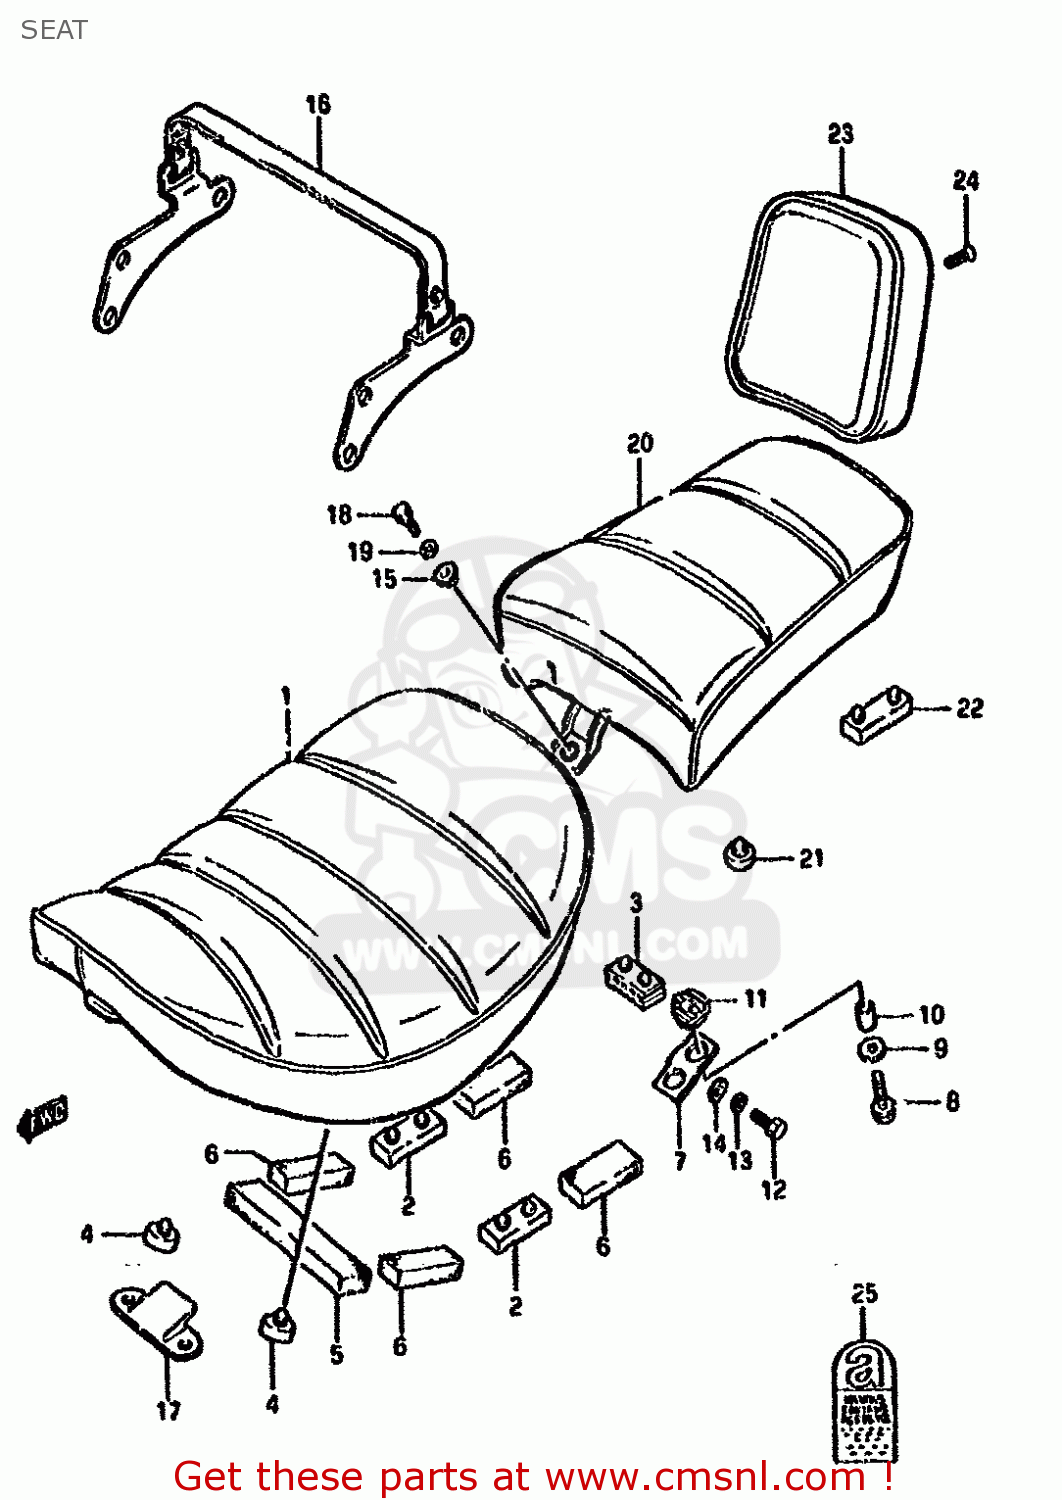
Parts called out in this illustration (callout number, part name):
1	SEAT SET
2	CUSHION,SEAT
3	CUSHION,SEAT(40X20X15)
4	CUSHION,FR
5	CUSHION,CTR FR
6	CUSHION,CTR SIDE
7	BRACKET,SEAT RR
8	BOLT
9	WASHER
10	COLLAR,SEAT(TS-5A1-02273)
11	CUSHION,SEAT RR BRACKET
12	SCREW
13	WASHER,LOCK
14	WASHER
15	WASHER
16	BAND,SEAT
17	PLATE,SEAT HOOK FR
18	BOLT
19	WASHER,LOCK
20	SEAT SET,PILLION
21	CUSHION,SEAT
22	CUSHION,SEAT
23	PAD ASSY,SEAT
24	SCREW
25	LABEL,ASBESTOS WARNING
